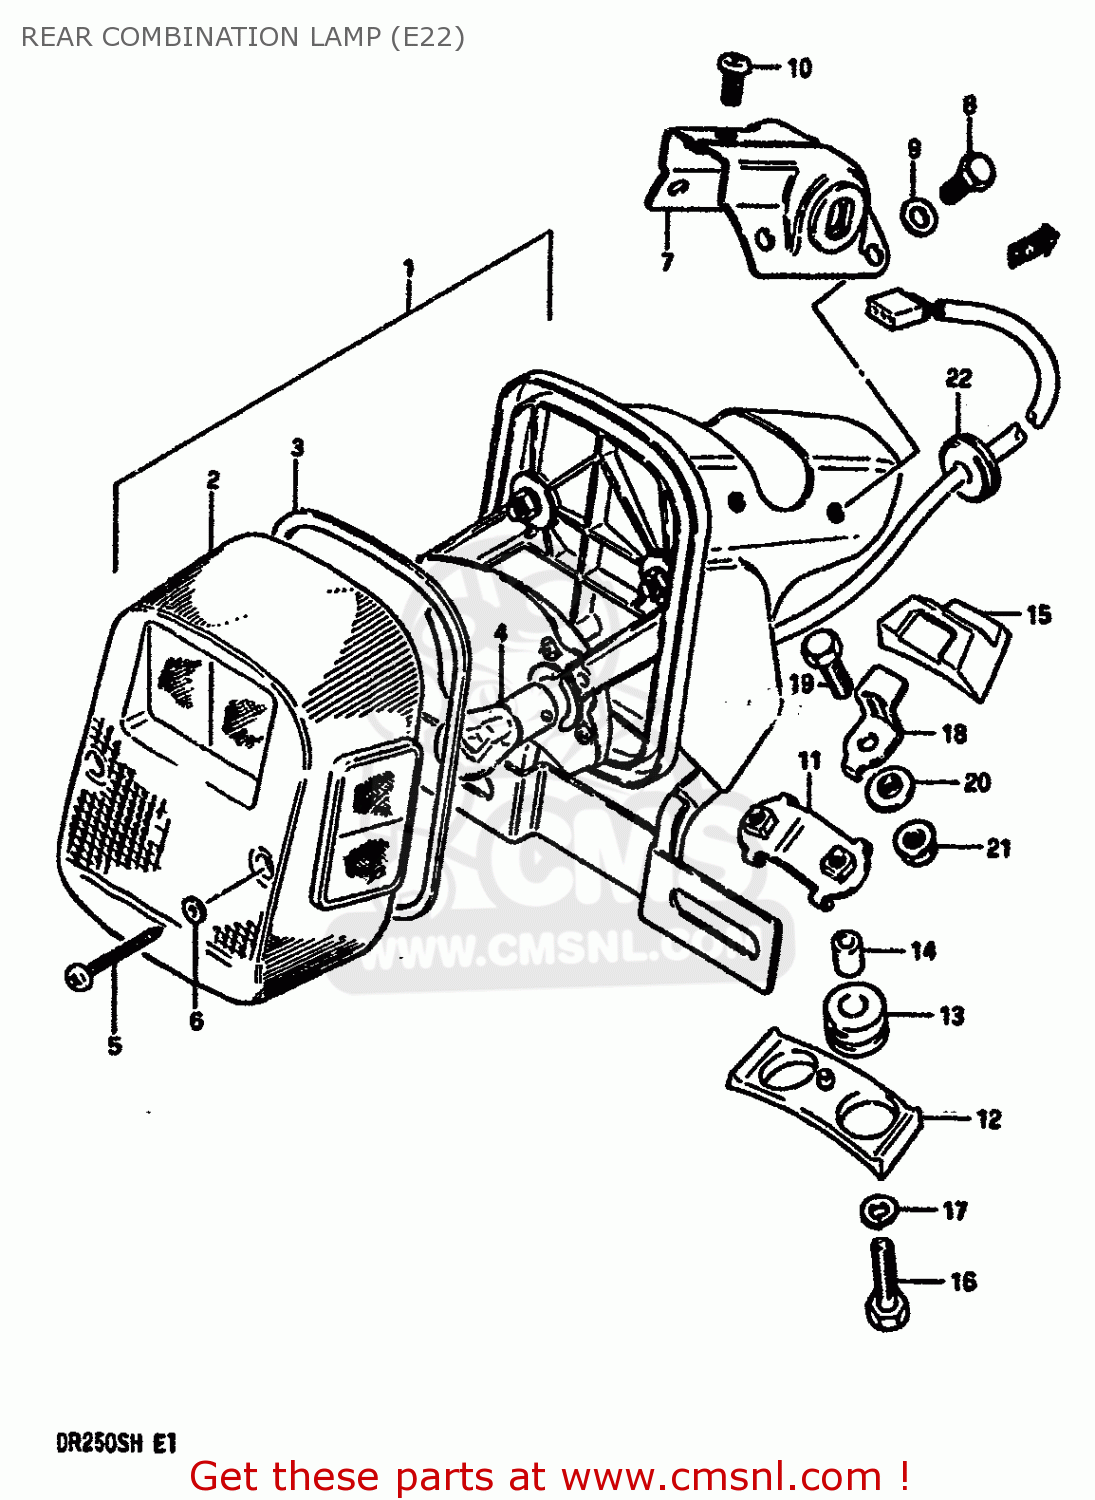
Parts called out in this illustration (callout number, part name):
1	LAMP ASSY,REAR COMBINATION
2	LENS
3	GASKET (NAS)
4	BULB(12V21/5W)
5	SCREW
6	GASKET (NAS)
7	PLATE
8	BOLT
9	WASHER
10	SCREW 6X12
11	PLATE
12	CUSHION
13	CUSHION
14	SPACER
15	CUSHION,REAR COMBINATION LAMP
16	BOLT
17	WASHER,LOCK
18	PLATE,RR COMBINATION LAMP
19	BOLT
20	WASHER,LOCK
21	NUT
22	GROMMET
